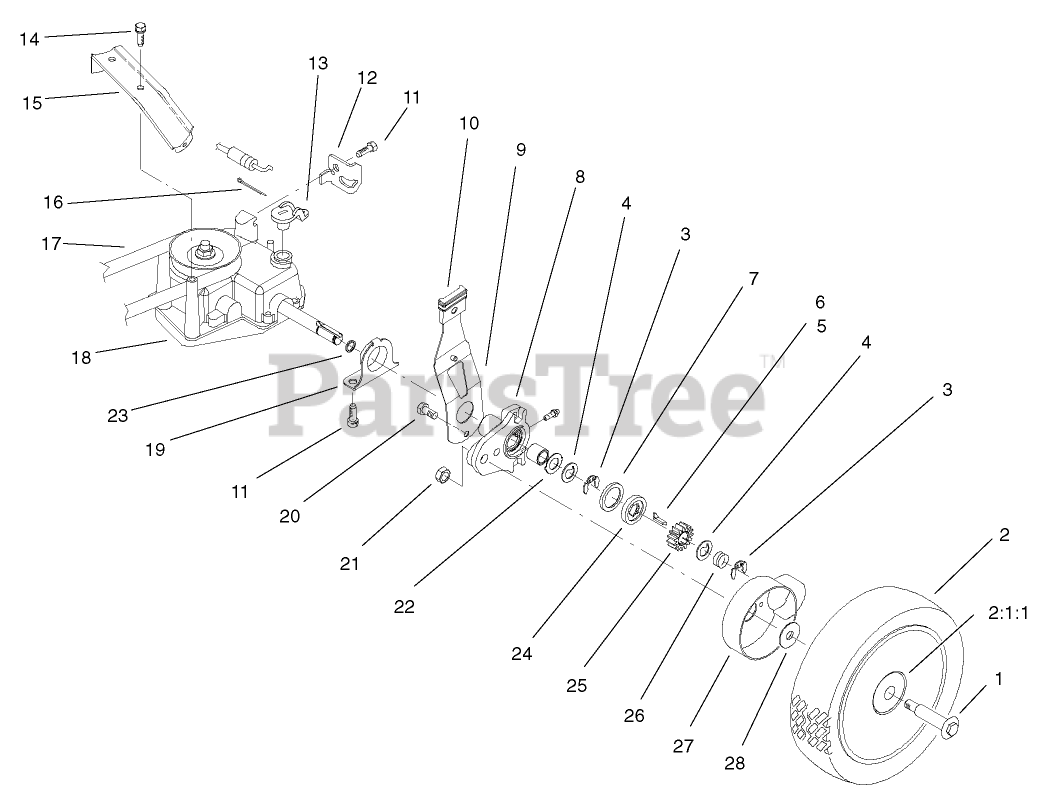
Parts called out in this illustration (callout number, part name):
1	BOLT-SHOULDER
2	WHEEL AND GEAR ASM
2:1	Wheel ASM
2:1:1	BUSHING
3	RING-RETAINING,CLIP
4	WASHER-THRUST, KEYED
5	KEY-ROCKING, LH
6	KEY-ROCKING, RH
7	RING-FRICTION
8	PIVOT ARM ASM
9	SPRING ARM ASM
10	KNOB-ARM
11	SCREW-HWHTF
12	RETAINER-CABLE
13	LEVER-SHIFT
14	SCREW-HWHTF
15	BRACKET-GUIDE, BELT
16	PIN-COTTER
17	V-BELT
18	GEARCASE ASM
19	CAP-END
20	SCREW-HWH
21	LOCKNUT
22	WASHER-ARM, PIVOT
23	O-RING
24	WASHER-CLUTCH
25	GEAR-PINION
26	SPRING-COMPRESSION
27	COVER-WHEEL
28	SPACER-COVER, WHEEL
